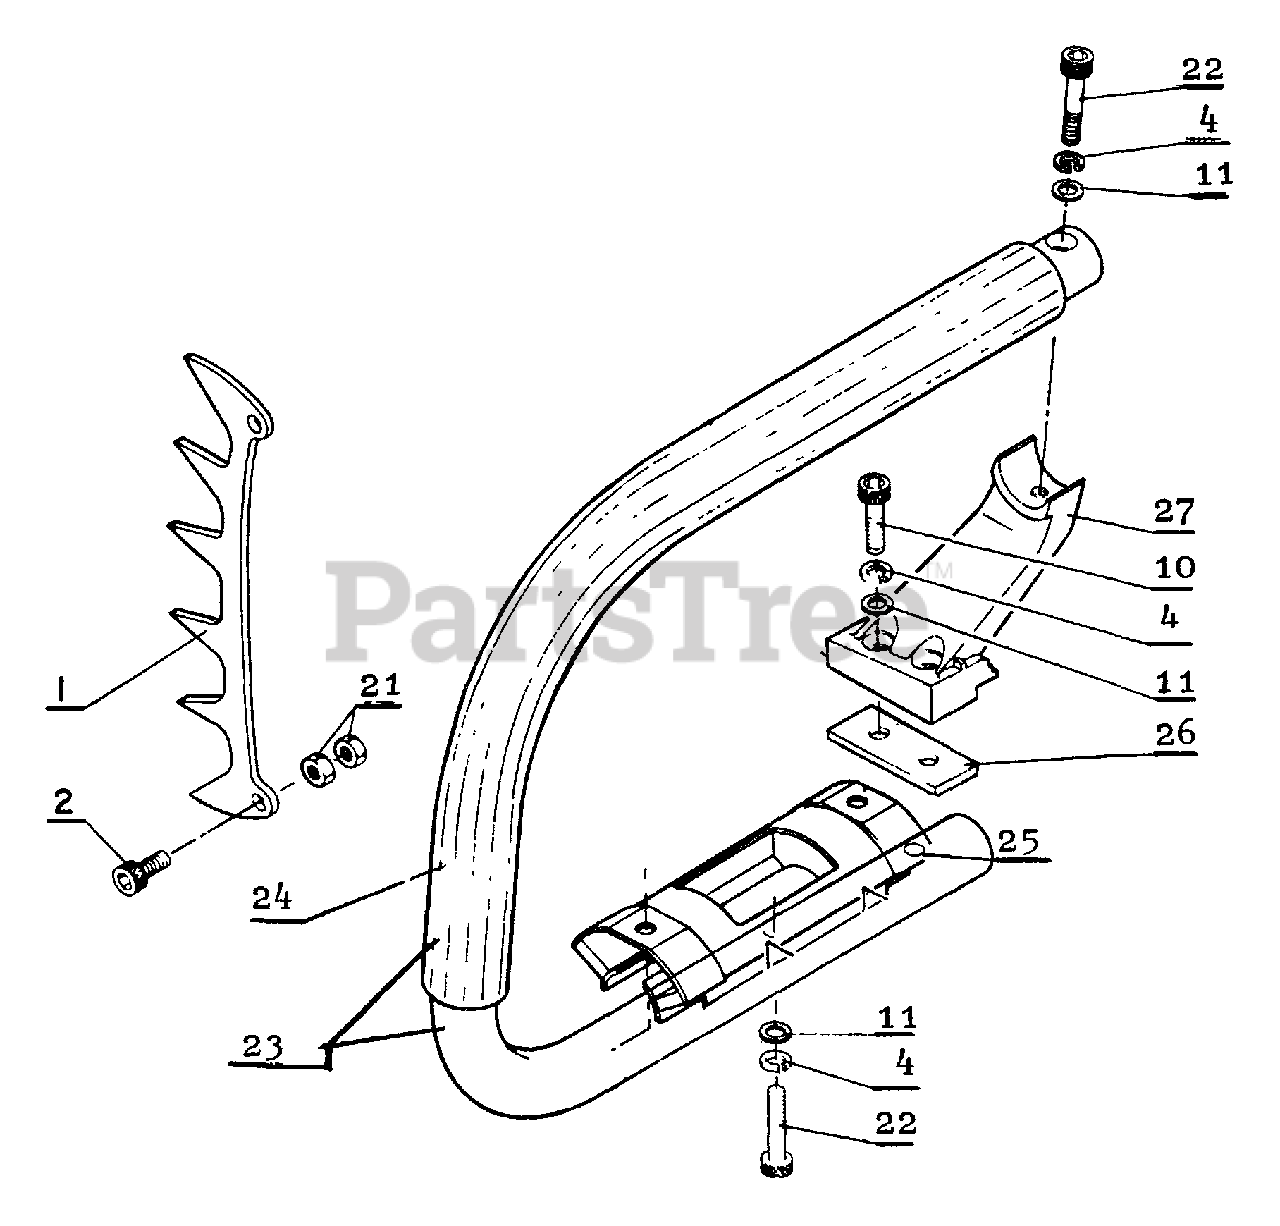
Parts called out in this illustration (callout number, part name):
1	SPIKE
2	SCREW - 5X15
4	LOCKWASHER - 5
10	SCREW - 5X20
11	WASHER - 5
21	LOCKNUT - 5
22	SCREW - 5X25
23	HANDLE - FRONT
24	HANDLE - FRONT
25	ADAPTOR, CRANKCASE
26	Rubber cushion, front handle
27	HANDLE, SUPPORT
